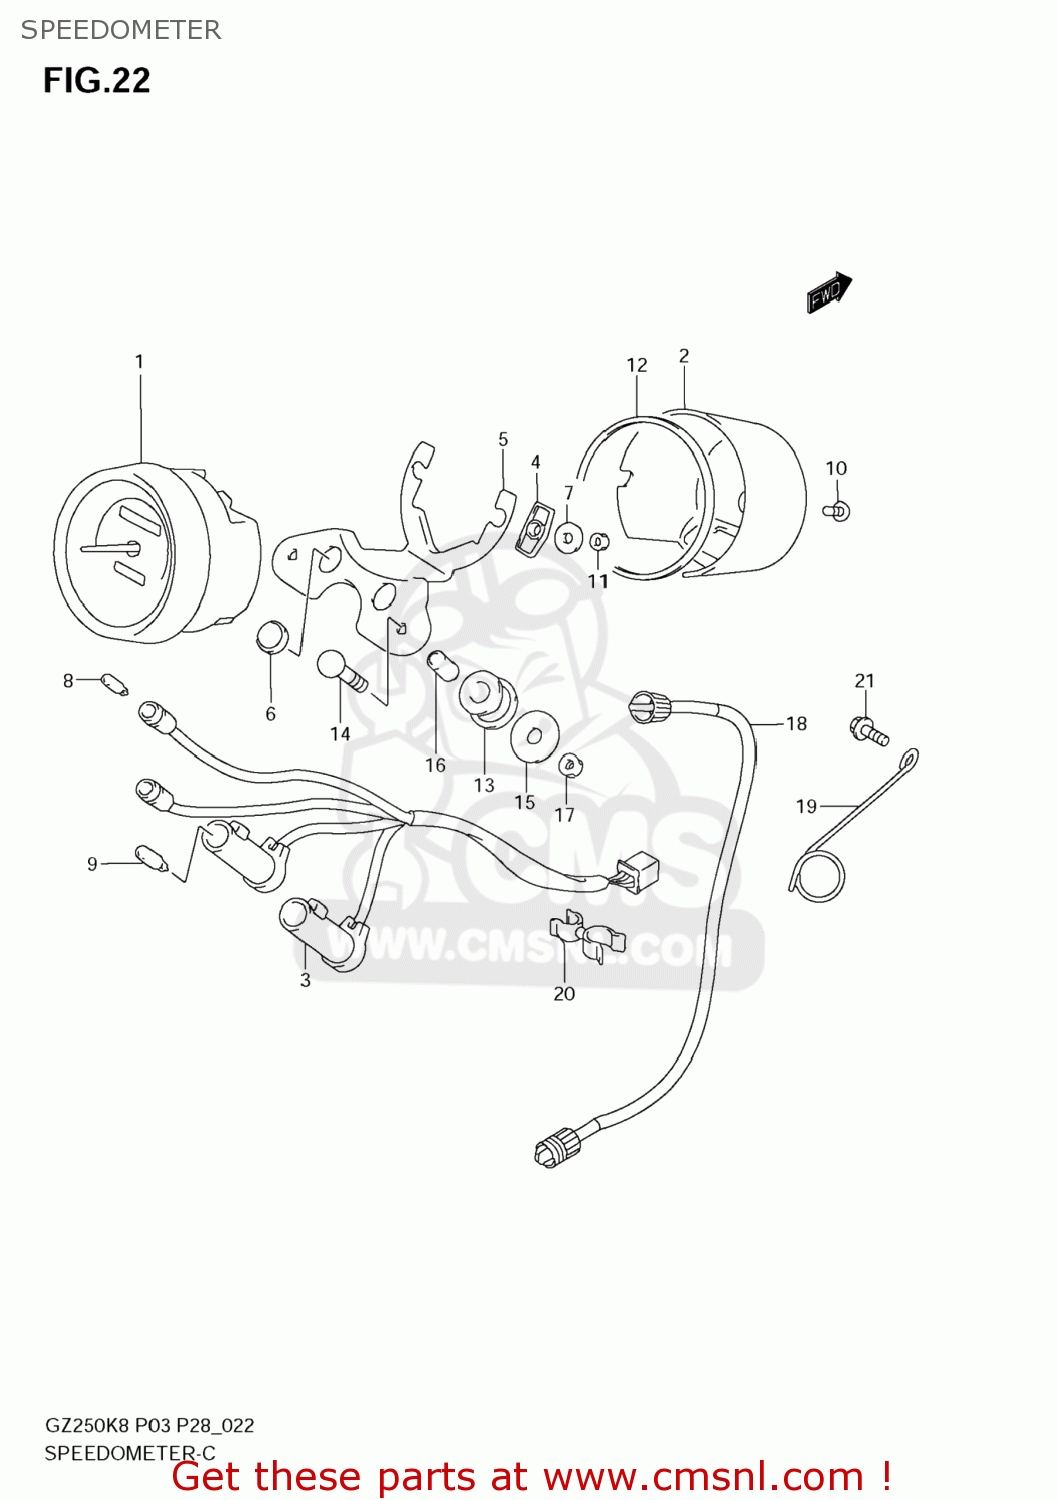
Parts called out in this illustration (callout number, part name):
1	SPEEDOMETER (MILE/KILO)
2	COVER, UNDER
3	SOCKET, ASSY
4	CUSHION,DAMPER
5	BRACKET, METER
6	LENS, GREEN
7	WASHER
8	BULB(12V3.4W,T10)
9	BULB(12V1.7W,T6.5)
10	SCREW,METER
11	NUT
12	PACKING (NAS)
13	CUSHION,METER BRACKET
14	BOLT(6X30)
15	WASHER(6.5X28X1.6)
16	SPACER(6.5X10X16.5)
17	NUT
18	CABLE ASSY,SPEEDOMETER
19	GUIDE,SPEEDOMETER CABLE
20	CLAMP
21	BOLT
